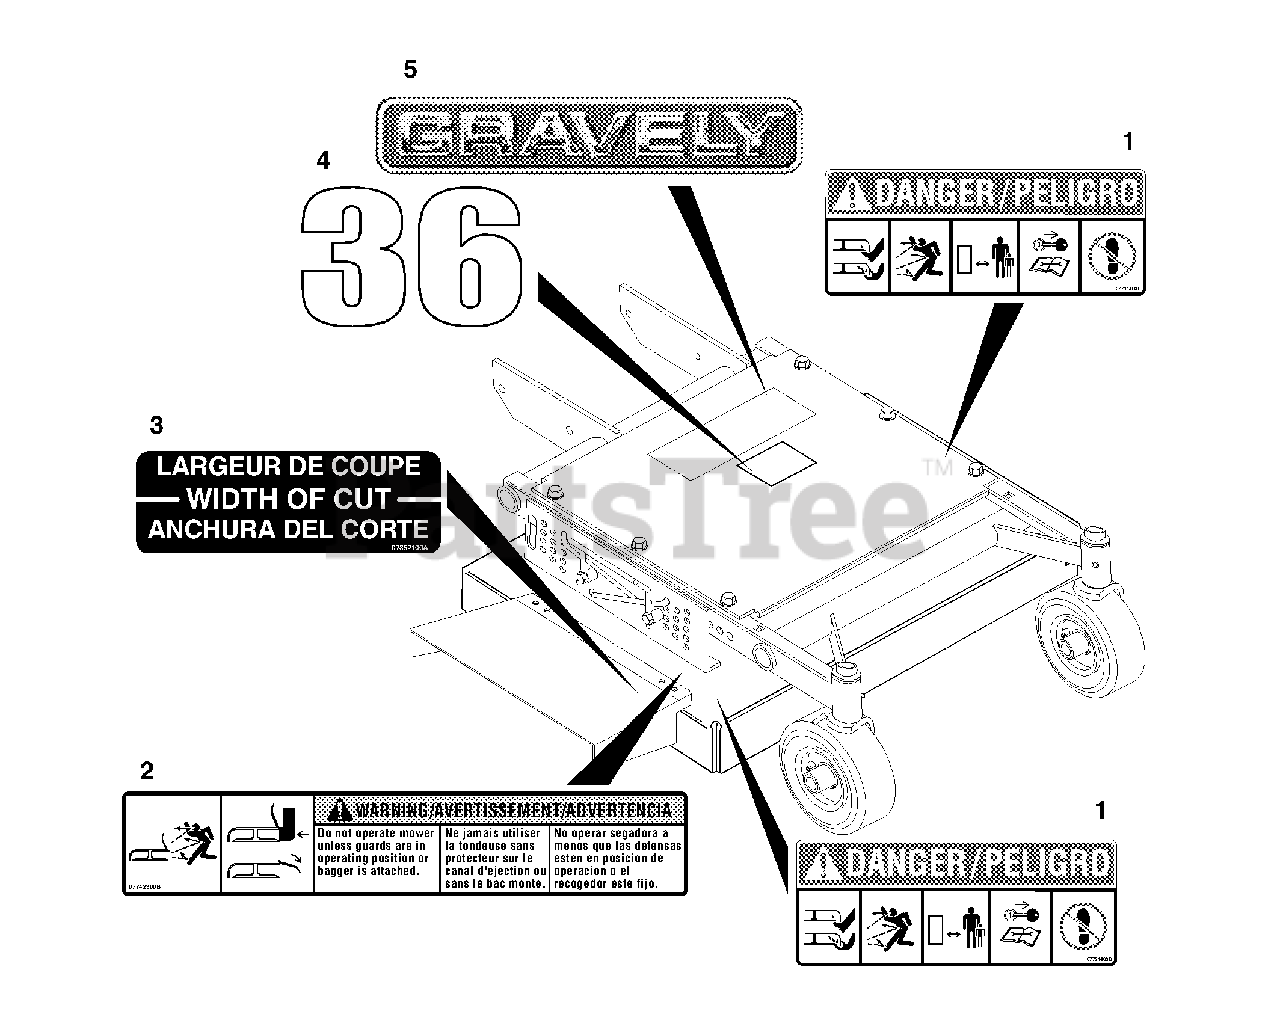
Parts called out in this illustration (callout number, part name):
1	Decal, Mower Pan Head Danger
2	Decal, Warning
3	Decal, Width of Cut
4	Decal, 36
5	Decal, 15" Gravely Logo
